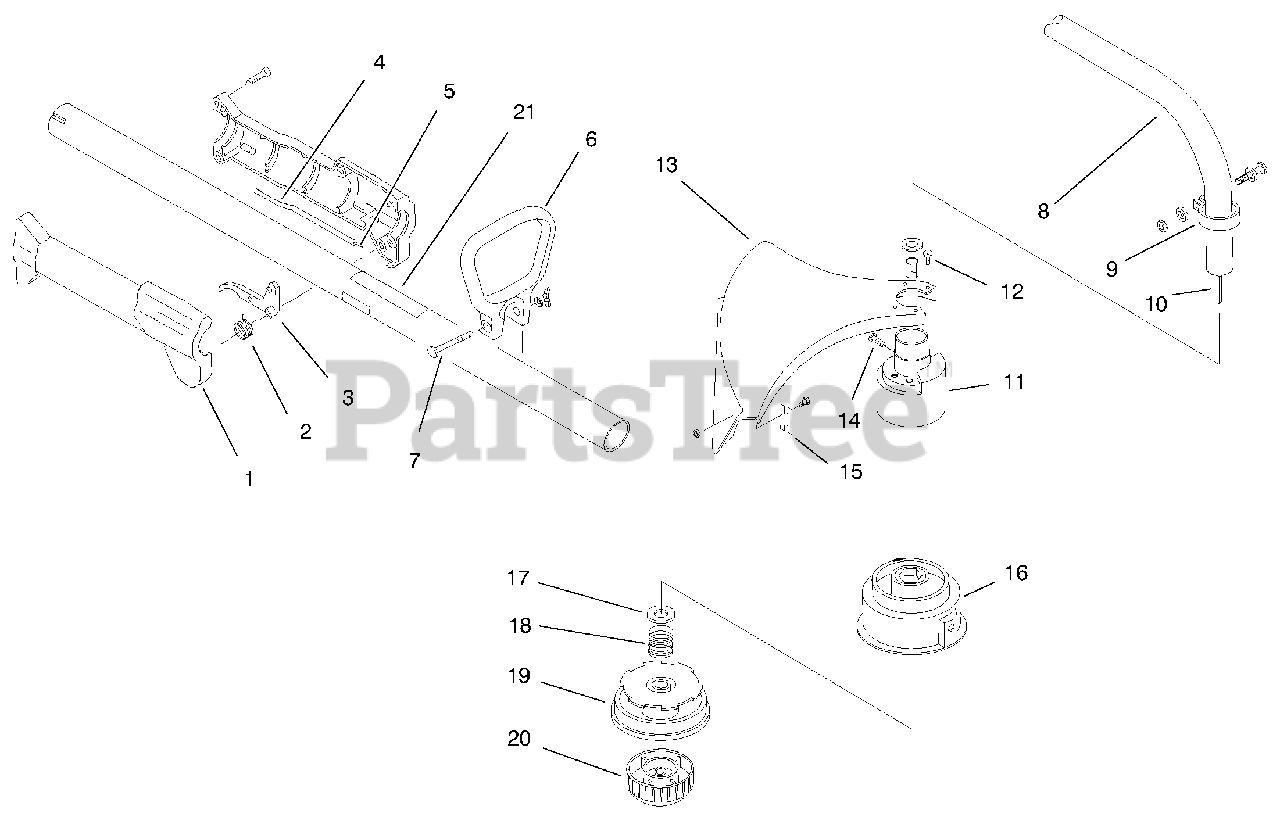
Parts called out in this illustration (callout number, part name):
1	Throttle Housing & Trigger Asm.
2	Throttle Trigger Spring
3	Throttle Trigger
4	Throttle Cable Housing
5	Throttle Cable
6	D-Handle
7	D-Handle Hardware Asm.
8	Drive Shaft Housing Asm.
9	Clamp Asm.
10	Flexible Drive Shaft
11	Bushing Housing Asm.
12	Guard Mounting Screw
13	Guard and Blade Asm. (Incl. Ref. #16)
14	Anti-Rotation Screw
15	Blade Asm.
16	Outer Spool and Eyelet Asm.
17	Retainer
19	Inner Reel
20	Bump Head Knob Asm.
21	Decal-Safety Symbols
